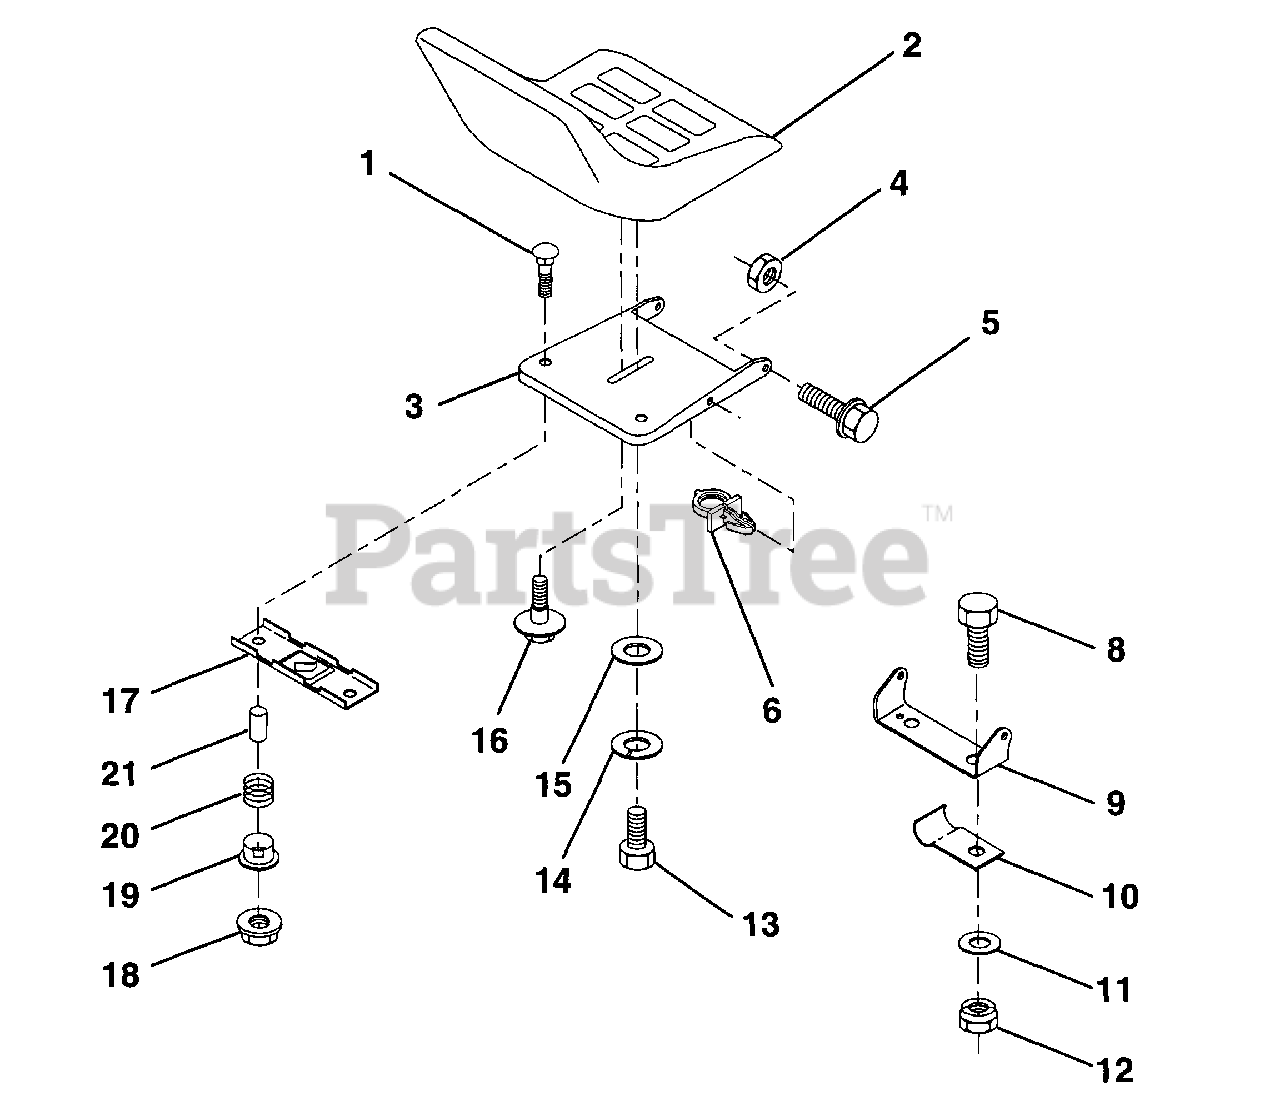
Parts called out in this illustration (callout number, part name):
1	Bolt, Carriage 1/4-20 x 1-3/8
2	Seat
3	Pan, Seat
4	Locknut, Hex w/Ins 5/16-18
5	Bolt, Shoulder 5/16-18 UNC
6	Clip, Push-in
8	Bolt, Fin Hex 3/8-16 UNC x 1
9	Bracket, Pivot Seat
10	Clip, Insulated
11	Washer 12/32 x 2 x 10 Ga.
12	Nut, Lock Hex w/Wsh 3/8-16
13	Bolt Hex 1/2-13 x 7/8
14	Washer Lock Hvy. Hlicl Spring 1/2
15	Washer, 17/32 x 1-3/16 x 12 Ga.
16	Bolt, Shoulder
17	Bracket, Switch, Mounting
18	Nut, Hex Large Flange Lock
19	Bushing, Snap
20	Spring, Compression
21	Spacer, Split 28 Id. x .88 Lg.
